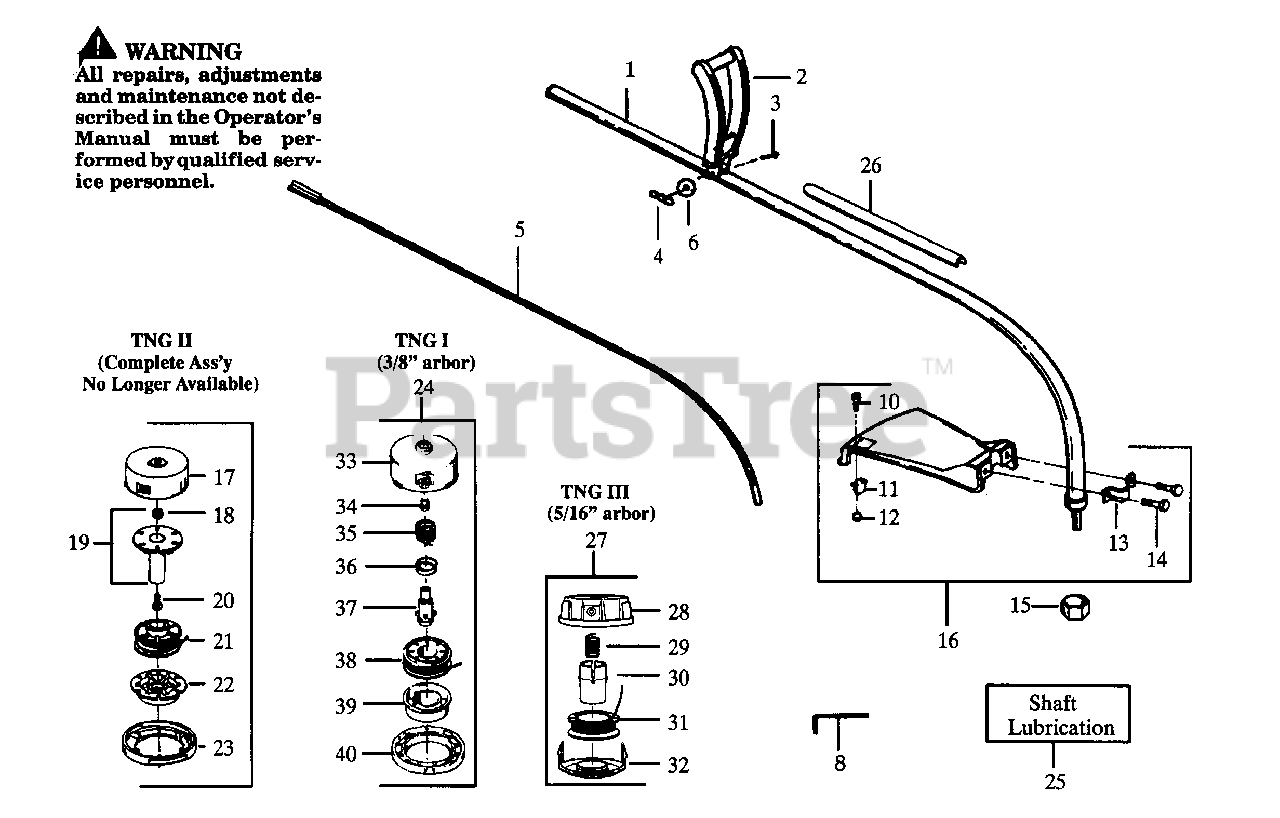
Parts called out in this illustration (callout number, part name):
1	Drive Shaft Housing Model GTI 15
1	Drive Shaft Housing Model GTI 15T
4	Wing Nut
5	Drive Shaft Model GTI 15
5	Drive Shaft Model GTI 15T
8	Hex Wrench (5/32)
11	Line Limiter
12	Nut
15	Dust Cup
16	Shield Kit Ass'y. (Inc 10,11,12,14) Model GTI 15
16	Shield Kit Ass'y. (Inc 10,11,12,14) Model GTI 15T
17	Hub Ass'y.
19	Locking Plate Kit
21	Spool w/Line
22	Release Button
24	Cutting Head Ass'y.
25	Shaft Lubrication
26	Shaft Warning Decal
27	Cutting Head Ass'y. (5/16" arbor) Incl. 28-32 Model GTI 15T
28	Hub Ass'y.
30	Release Button
31	Spool w/Line
33	Hub
34	Line Saver
36	Spring Cap
37	Diver Gear
38	Spool w/Line
39	Release Button
